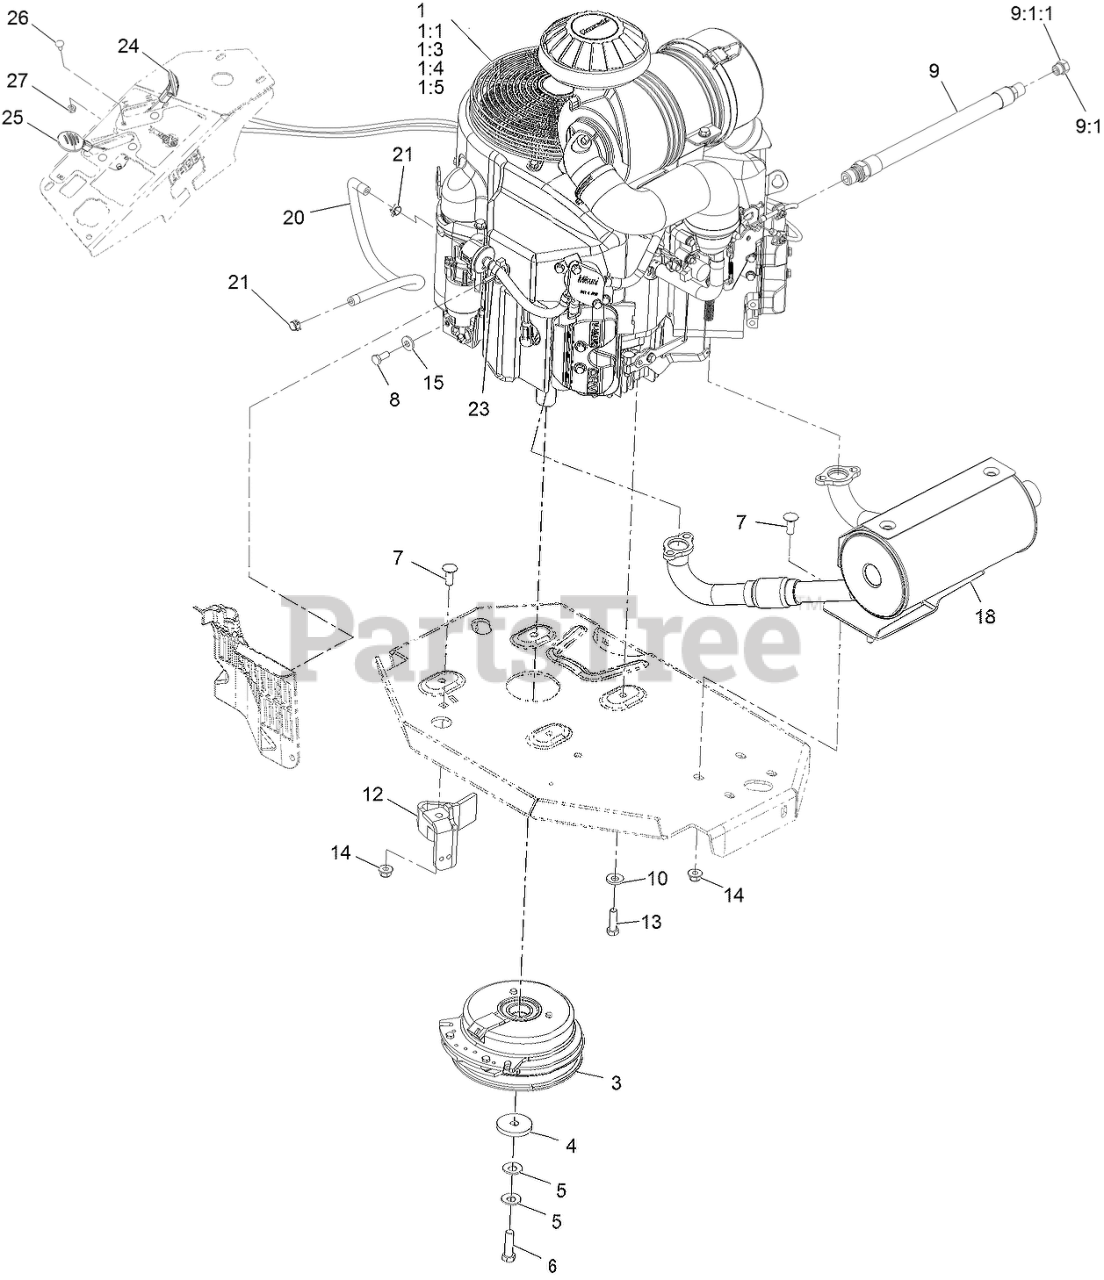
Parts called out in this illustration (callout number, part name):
1:1	Kawasaki 49065-2078 Engine Oil Filter
1:3	Kawasaki 49019-0031 Fuel Filter
1:4	Kawasaki 11013-7039 Safety Filter
1:5	Kawasaki 11013-7038 Air Filter
3	CLUTCH KIT
4	WASHER-CLUTCH
5	WASHER-SPRING
6	SCREW-HH 7/16-20 X 1 1/2 W/LOCTITE
7	SCREW-CARR
8	SCREW-HH
9	ENGINE OIL DRAIN HOSE ASM
9:1	PLUG-HH
9:1:1	O-RING
10	WASHER-BELLEVILLE
12	CLUTCH-ANCHOR
13	SCREW-HH
14	NUT-HF, NI
15	WASHER-SPRING
18	MUFFLER, FX850/801 FLEX
20	HOSE-FUEL
21	CLAMP-HOSE
23	CLAMP-HOSE
24	ASM, CHOKE CABLE
25	ASM,THROTTLE CABLE
26	BOLT-CARR
27	NUT-LOCK, NI
